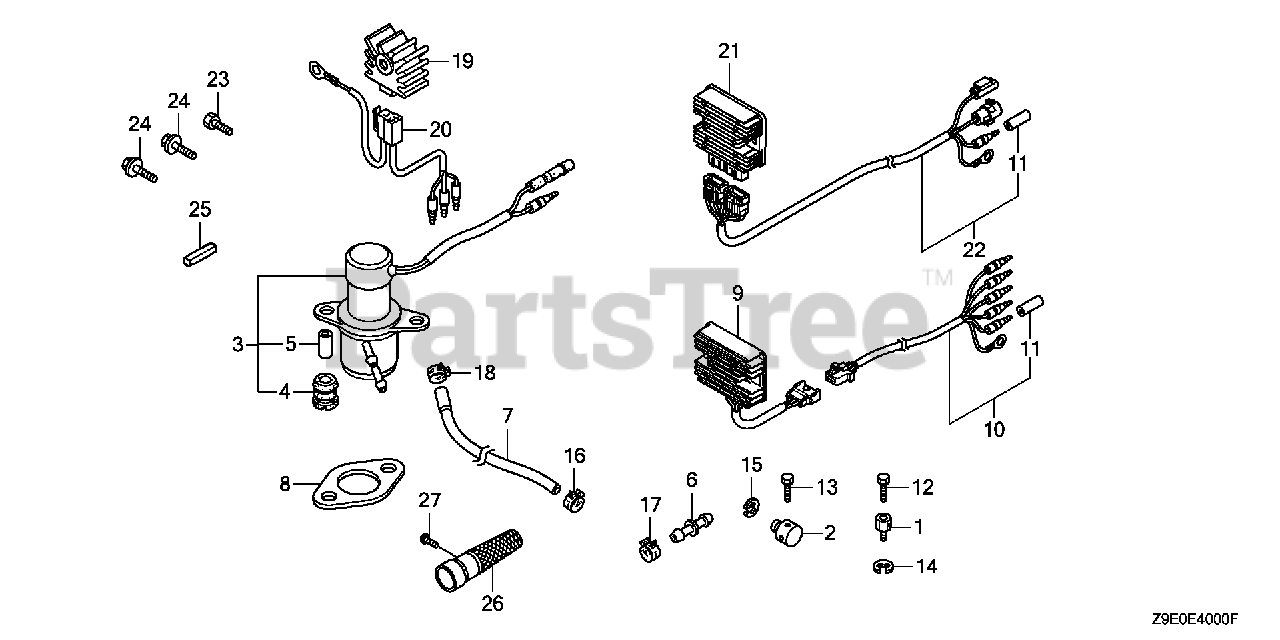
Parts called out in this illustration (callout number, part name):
1	HOLDER, WIRE
2	HOLDER, CABLE
8	GASKET, EX. PIPE Use up to Engine SN 2949254.
8	GASKET, EX. PIPE (WACKER)
9	RECTIFIER ASSY., REGULATOR (20A)
10	SUB-WIRE HARNESS ASSY.
11	PLUG, CONNECTOR (OUTER) (ENGINE NO.)
12	BOLT, RECESSED (4X6)
13	BOLT, RECESSED (4X6)
14	E-RING (5MM)
15	E-RING (5MM)
